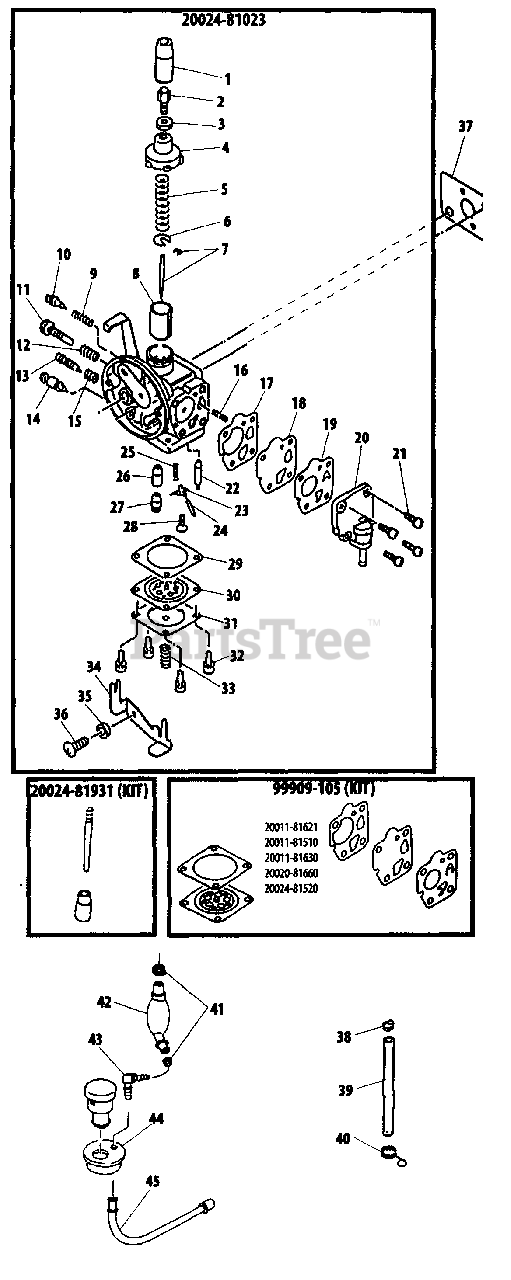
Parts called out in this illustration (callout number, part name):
1	GROMMET
2	NUT, CABLE ADJUST
3	LOCKNUT
4	CAP, CARBURETOR
5	SPRING
6	RETAINER
7	JET NEEDLE KIT
8	VALVE, THROTTLE
9	SPRING
10	SCREW, SLOW AIR
11	SCREW, IDLE ADJUST
12	SPRING
13	SCREW, IDLE ADJUST
14	VALVE, OVERFLOW
15	SCREW, IDLE ADJUST
16	SPRING
17	GASKET, METERING
18	DIAPHRAGM, METERING
19	VALVE, PUMP
20	BODY, PUMP
21	SCREW
22	VALVE, INLET NEEDLE
23	LEVER, METERING
24	PIN, METERING LEVER
25	SPRING
26	JET NEEDLE KIT
27	HOLDER, JET
28	SCREW, METERING LEVER PIN
29	GASKET
30	DIAPHRAGM
31	COVER, DIAPHRAGM
32	SCREW
33	SPRING
34	LEVER, TICKLER
35	COLLAR
36	SCREW
37	GASKET, INTAKE
38	RING, RETAINING - 6
39	PIPE
40	HOLDER, PIPE
41	RING, RETAINING
42	PIPE - FUEL
43	JOINT
44	GROMMET
45	PIPE - FUEL
